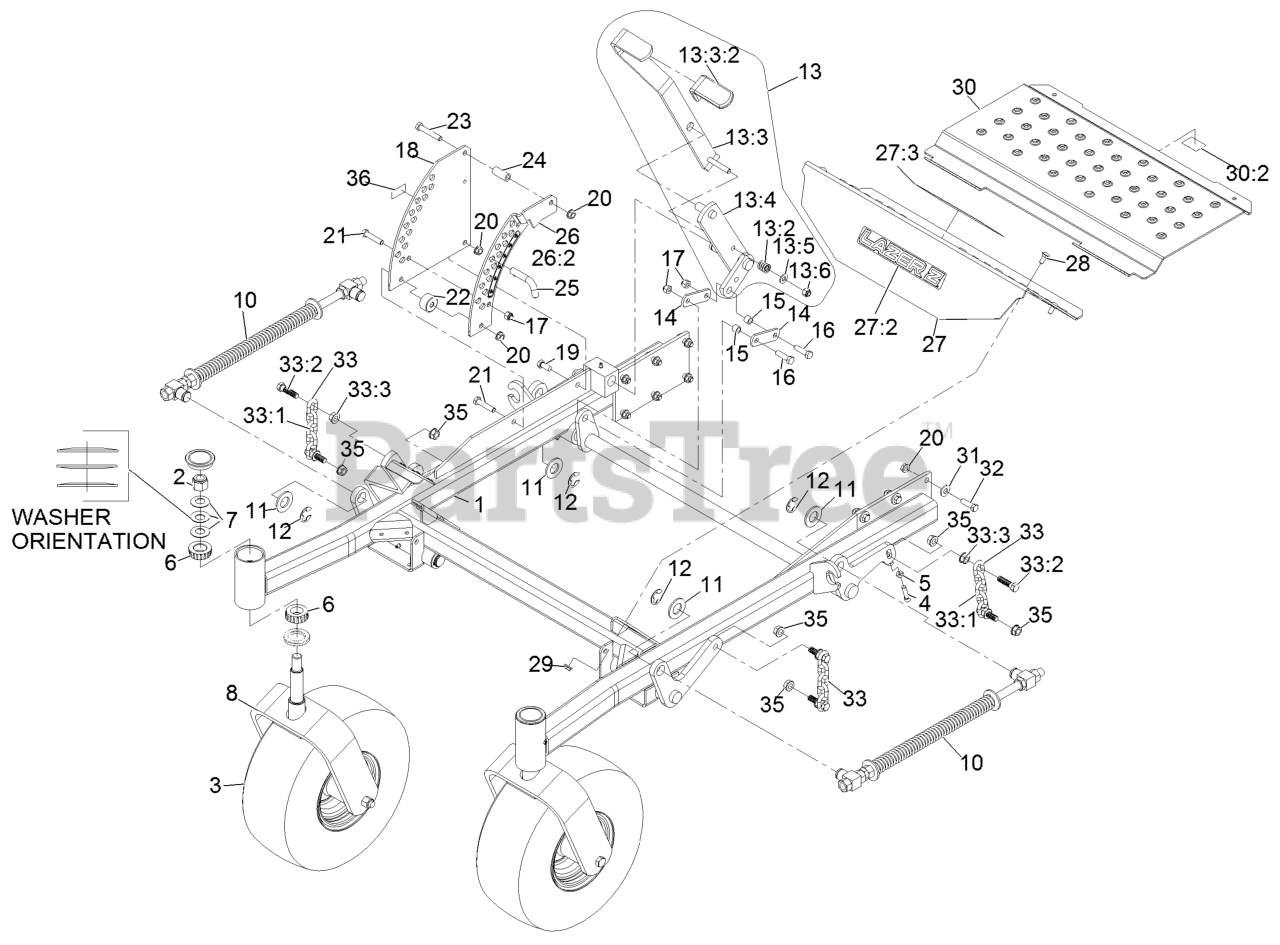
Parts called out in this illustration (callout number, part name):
1	ASM-FRT FRM 605
2	NUT-LOCK, NI
3	WHEEL & TIRE ASM
4	SCREW-HSH
5	NUT-JAM
6	Cone-Bearing Tapered Roller
7	WASHER-BELLVILLE
10	ASM,FRONT FRAME SPRING
11	WASHER-FLAT
12	RING-RETAINING, EXT
13	ASM,Deck Lift Handle
13:2	SPRING-COMPRESSION
13:3	LIFT LEVER/GRIP ASM
13:3:2	GRIP-LEVER, LIFT
13:4	WLD,ARM DECK LIFT
13:5	WASHER-FLAT
13:6	NUT-LOCK, NI
14	ARM-LIFT, DECK
15	BUSHING
16	SCREW-HH
17	NUT-LOCK, NI
18	PLATE-DECK LIFT NOTCHED O
19	SCREW-HH
20	NUT-HHF, WHIZ
21	SCREW-HH
22	Stop, Deck Height
23	SCREW-HH
24	BUSHING-LEVER, LIFT
25	PIN-HOC
26	PLATE-LIFT, DECK W/DECAL
26:2	DECAL-HEIGHT OF CUT
27	ASM, FLOORPAN FRONT W/DEC
27:2	DECAL, LAZER MODEL
27:3	DECAL-DANGER
28	BOLT-CARR
30	ASM, FLOORPAN LIFTOUT W/D
30:2	Decal-Guard
31	WASHER-BELLEVILLE
32	SCREW-HH
33	DECK CHAIN ASM
33:1	CHAIN-LIFT, DECK
33:2	SCREW-HH
36	Decal-Patent
